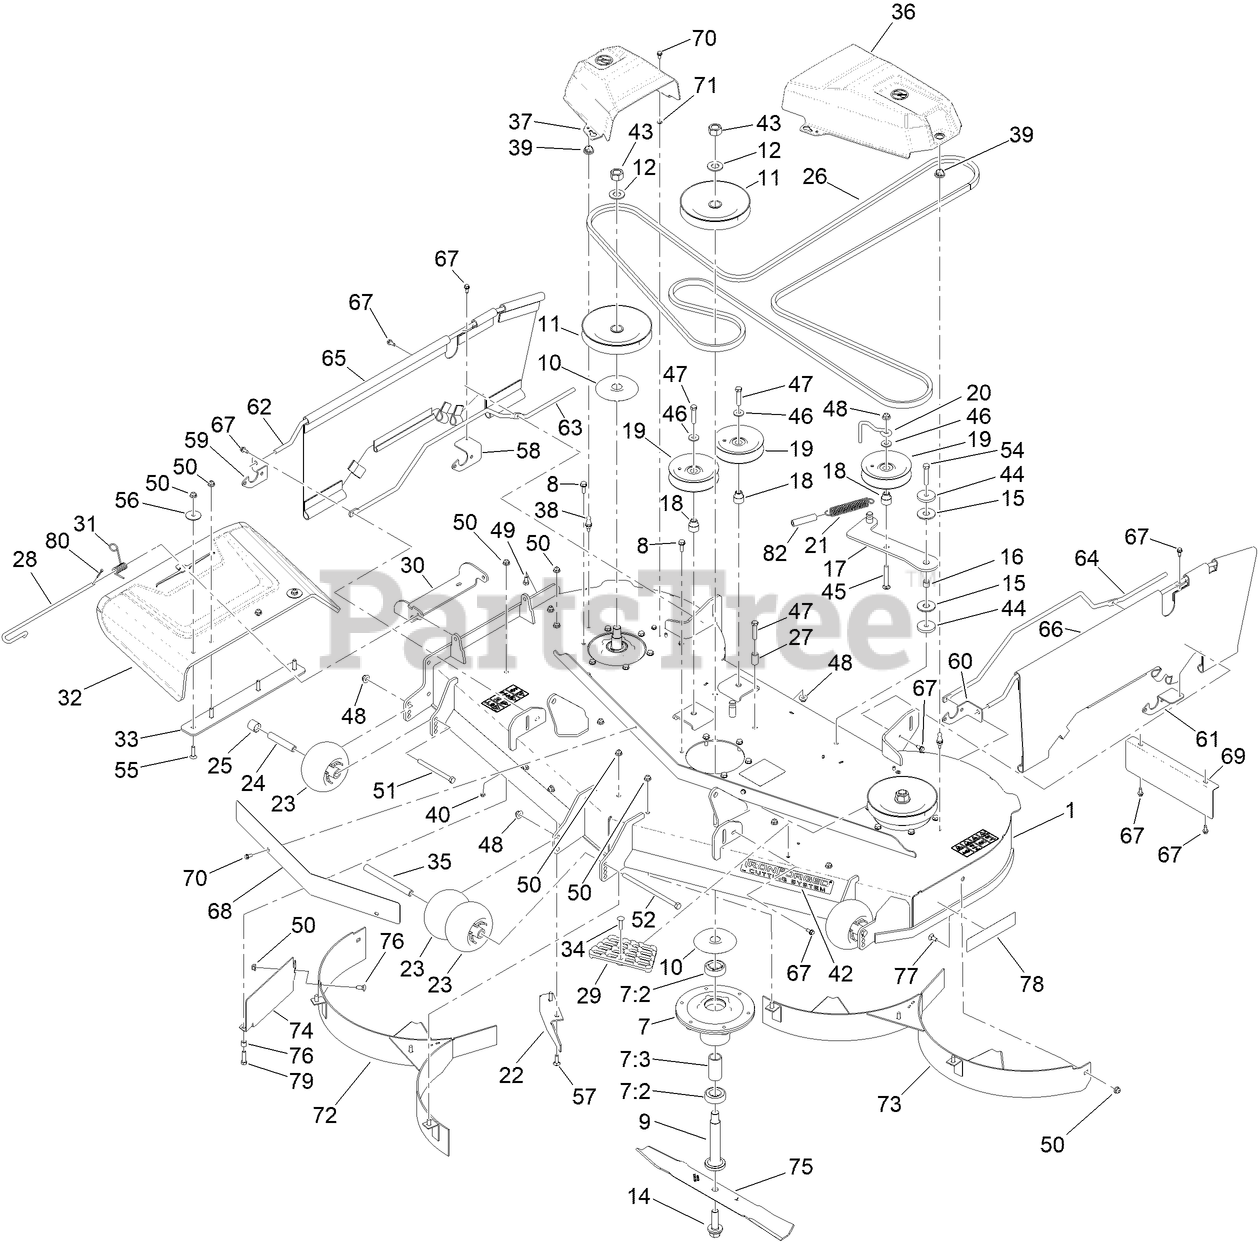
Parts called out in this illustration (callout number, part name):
1	60 IN DECK DECAL ASM
7	SPINDLE ASM
7:2	BEARING-BALL
7:3	SPACER-BEARING
8	SCREW-TAPTITE
9	SHAFT-SPINDLE
10	SHIELD-BEARING
11	PULLEY
12	WASHER
14	SCREW-BLADE
15	WASHER-FRICTION, COMPOSITE
16	SPACER
17	IDLER ARM ASM
18	BUSHING-IDLER
19	PULLEY-IDLER, FLAT
20	GUIDE-BELT, IDLER
21	SPRING-EXTENSION
22	BAFFLE-CUTOFF
23	ROLLER-SCALP, ANTI
24	TUBE-SPANNER
25	SPACER-AXLE, REAR
26	BELT-V
27	SPACER-FENDER
28	PIN-CHUTE
29	STEP-DECK
30	BRACKET-DEFLECTOR, UPPER
31	SPRING-TORSION
32	DEFLECTOR - MOLDED
33	PLATE-DEFLECTOR
34	BOLT-CARRIAGE
35	SPACER-WHEEL
36	COVER-BELT, LH
37	COVER-BELT, RH
38	STUD-BALL
39	GROMMET-BALL
40	NUT-LOCK
42	DECAL - IRON FORGED
43	NUT-HEX
44	WASHER-PLAIN
45	SCREW-CARR
46	WASHER-HARDENED
47	SCREW-HH
48	NUT-HF, NI
49	SCREW-HH
50	NUT-HF
51	SCREW-HH
52	SCREW-HH
54	HHCS 3/8-16 X 2, GR5, CZ
55	BOLT-CARRIAGE
56	WASHER-FLAT
57	SCREW-CARR
58	BRACKET-FRENCH GUARD
59	BRACKET-FRENCH GUARD
60	BRACKET-FRENCH GUARD
61	BRACKET-FRENCH GUARD
62	ROD-FRENCH GUARD
63	ROD-FRENCH GUARD
64	ROD-FRENCH GUARD
65	GUARD ASM-SIDE, POLY KNIT
66	GUARD ASM-SIDE, POLY KNIT
67	SCREW-HWH
68	PLATE-SHIELD FRONT
69	PLATE-GUARD REAR
70	SCREW-HWH
71	NUT-RETAINING
72	BAFFLE-RH
73	BAFFLE-LH
74	GUARD-BAFFLE
75	BLADE-MULCH, 20.50 INCH
76	SPACER
77	BOLT-CARR
78	DECAL-RECYCLER, 60 INCH
79	SCREW-HH
80	PIN-COTTER
82	HOSE-BREATHER
